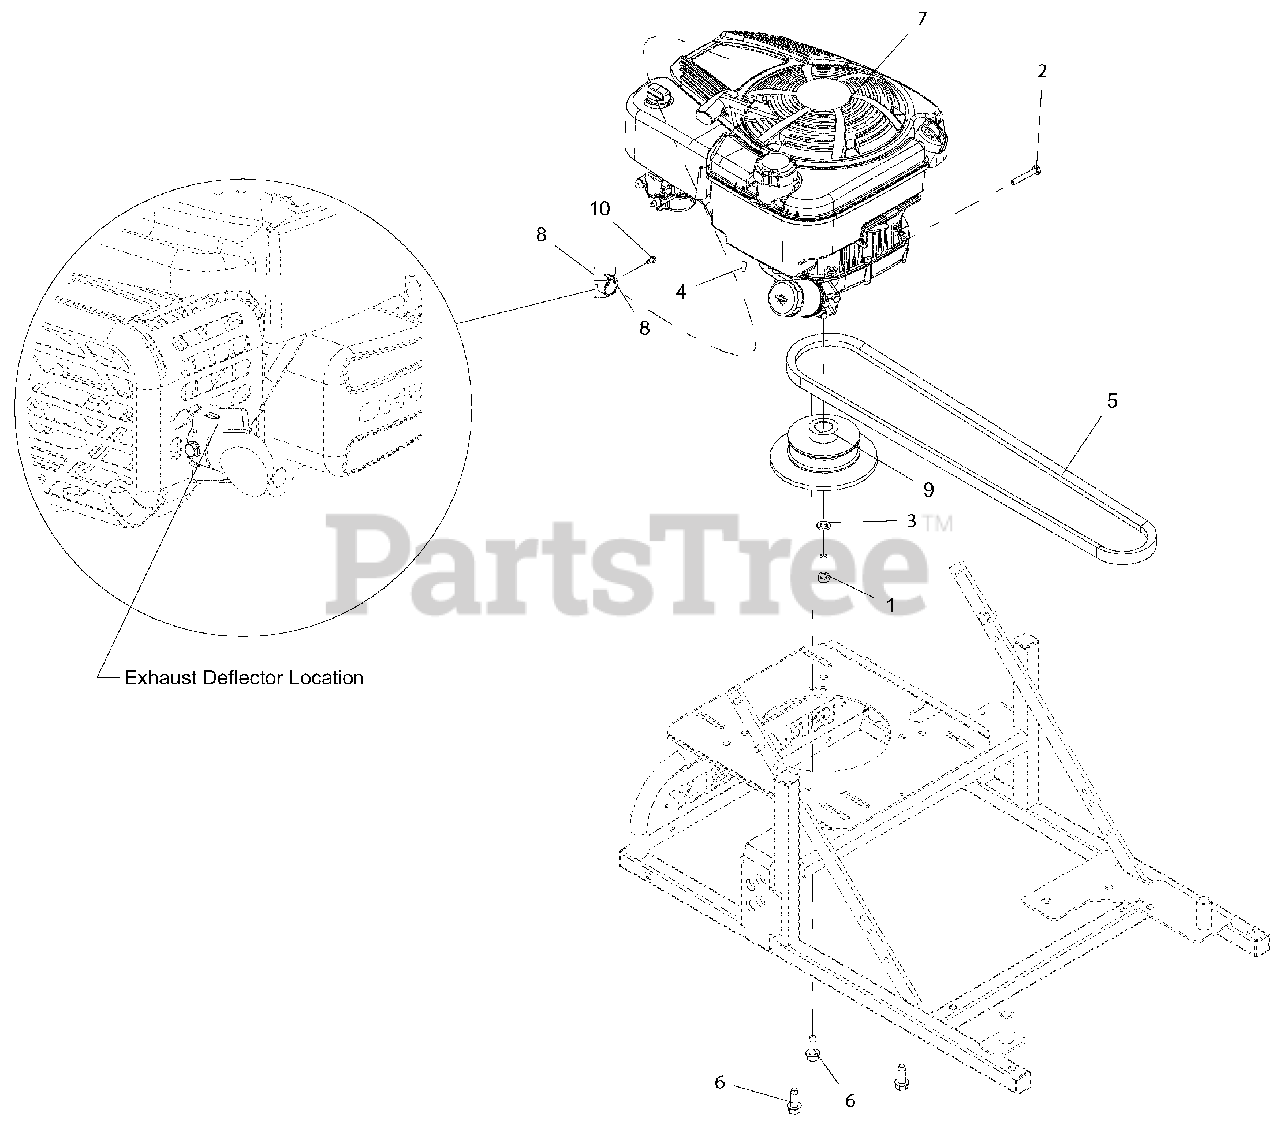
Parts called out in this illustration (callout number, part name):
1	BLT-HEX .38-24X1.25 GR8 TWZC
2	BLT-HEX .25-20X1.50 GR5 YWZC
3	WSHR-LK .38X.094 REG YWZC
4	KEY-WDRF .156X.625X.25 SAE 6
5	V-BELT, HB-WRAPPED
6	SCR-TAP .38-16X1.00 HWH TR YZ
7	ENGINE, B&S 190PRO 8.5 GT CARB
8	WMT-EXHAUST DEFLECTOR, HWM
9	SHEAVE, ENGINE , HW MOWER
10	SCR-TAP 8-32X.38 SL HWH YWZC
